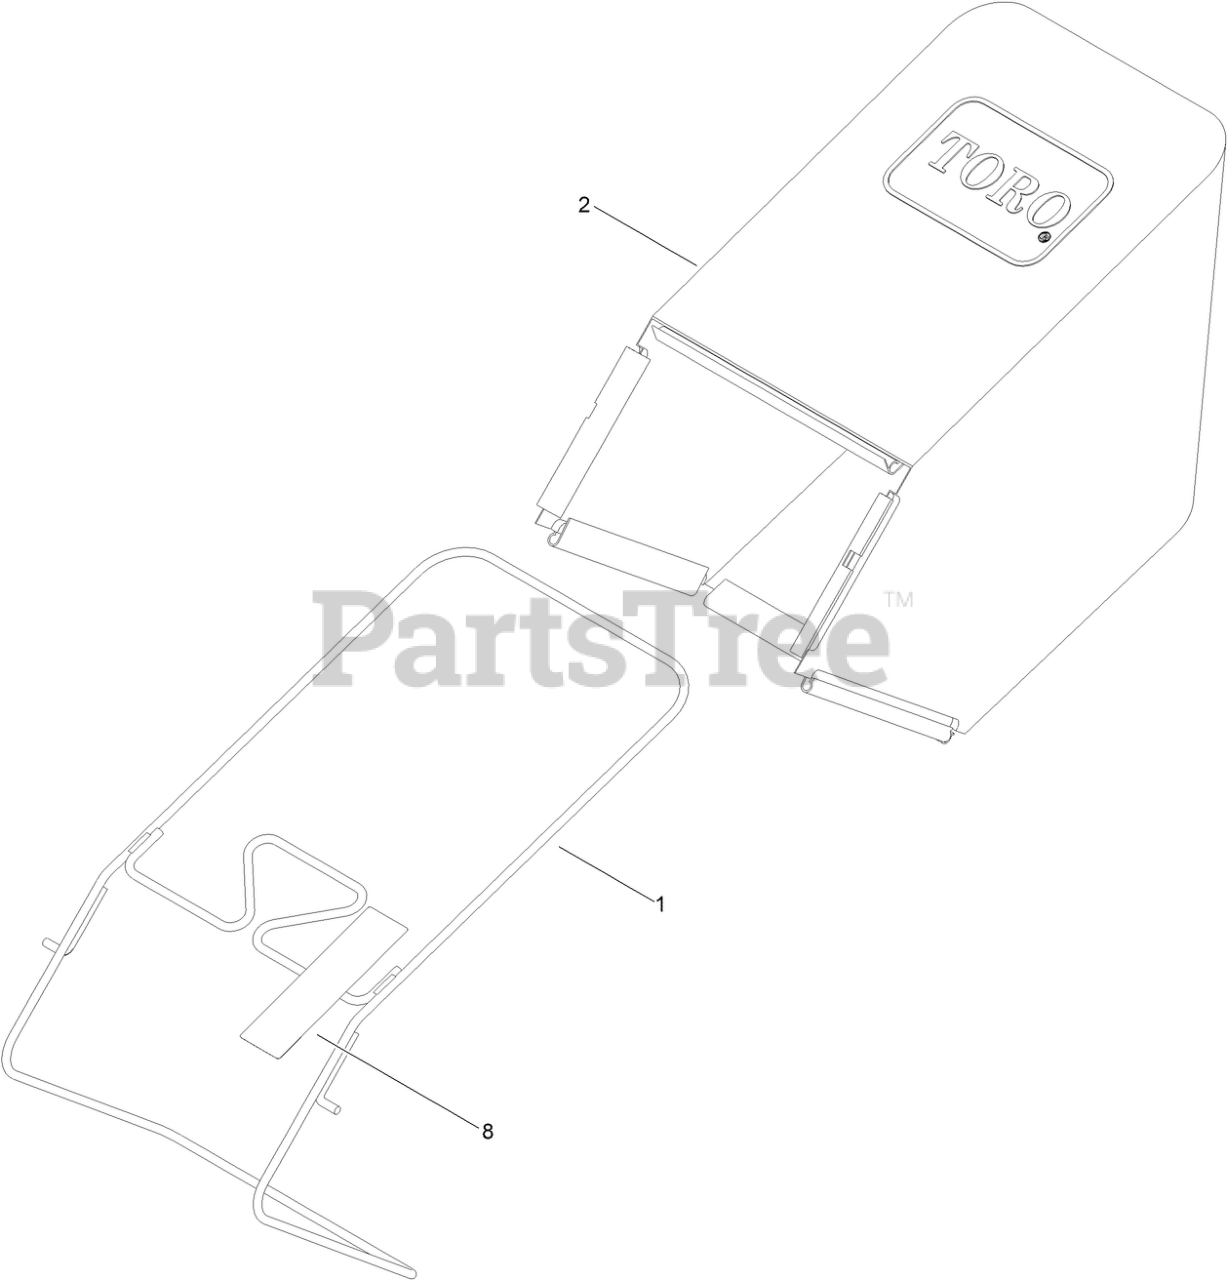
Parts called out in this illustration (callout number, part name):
1	FRAME-BAG
2	BAG ASM
8	Decal-Warning
